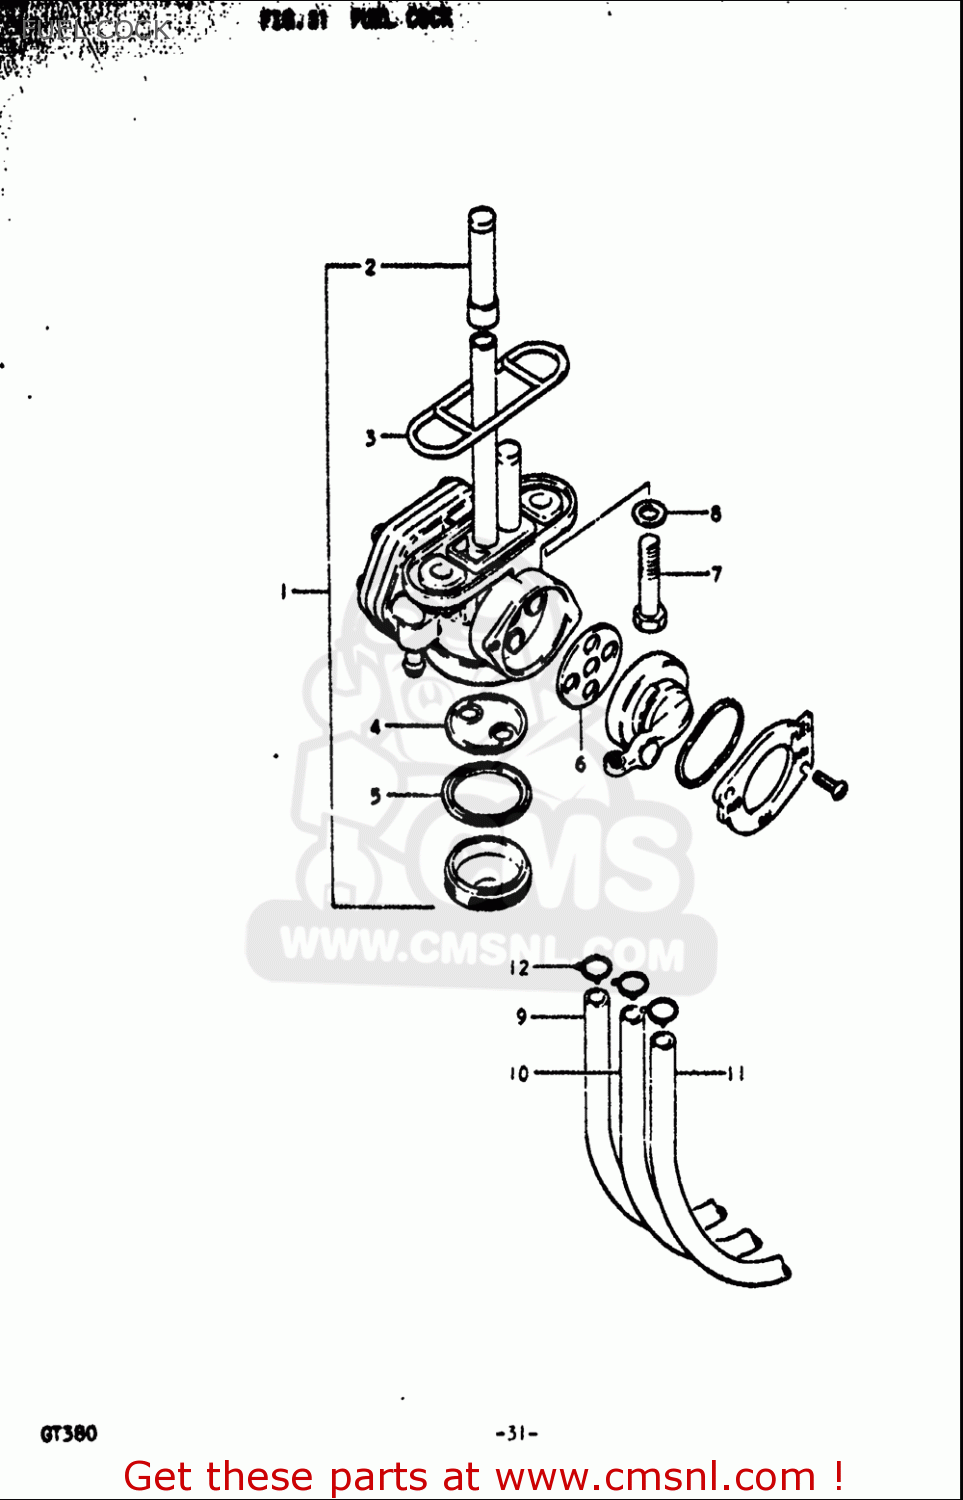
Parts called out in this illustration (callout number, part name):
2	FILTER
3	GASKET, FUEL COCK (NAS)
4	FILTER,CUP
5	GASKET,CUP (NAS)
6	GASKET,FUEL COCK LEVER (NAS)
7	BOLT
8	GASKET(5.8X13X1.2) (NAS)
9	HOSE(5X8.2X2000)
10	HOSE(5X9X600)
11	HOSE(5X8.2X600)
